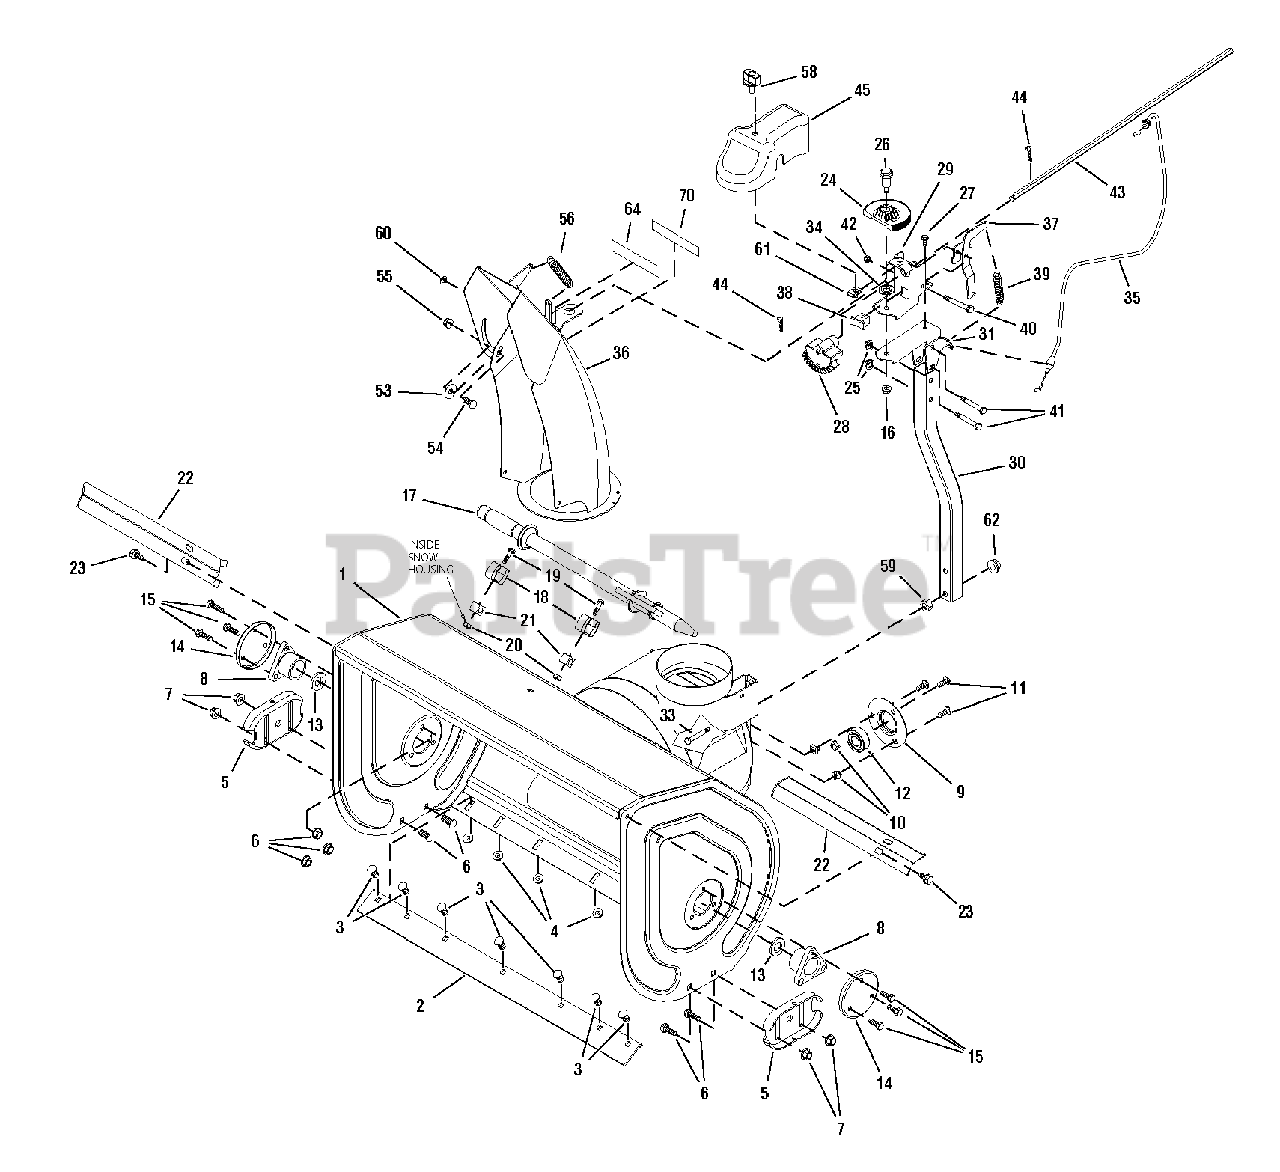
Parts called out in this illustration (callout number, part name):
1	HOUSING ASSEMBLY, 26"
1	HOUSING ASSEMBLY, 28"
1	HOUSING ASSEMBLY, 30"
1	HOUSING ASSEMBLY, 32"
2	BLADE, Scraper, 26"
2	BLADE, Scraper, 28"
2	BLADE, Scraper, 30"
2	BLADE, Scraper, 32"
3	CARRIAGE BOLT, 5/16-18 x 5/8 G5
4	NUT, Hex Flange 5/16-18 Two-Way Lock
5	SKID, Show Reversible
6	CARRIAGE BOLT, 3/8-16 x 3/4 G5
7	NUT, Hex Flange 3/8-16 ESNA
8	BEARING, Flange
9	BEARING RETAINER
10	RETAINER, Nut, 5/16-18
11	SCREW, Hex Whiz Lock Flange 5/16-18 x 3/4
12	BEARING
14	CAP, Bearing
15	CAPSCREW, Hex Head 5/16-18 x 7/8 G5
16	NUT, Hex Flange 5/16-18 Whiz Lock
17	STICK, Cleanout w/Brush
18	CLIP, Retainer
19	SCREW, Hex Washer Head Slot #10C x 1-1/4 G2
20	NUT, Hex Lock 10-24 w/Nylon Insert
21	BLOCK, Universal Pivot
22	CUTTER, Drift w/Tabs
23	SCREW, Hex Washer Head Taptitte 5/16-18 x 3/4
24	GEAR, 13 Tooth
25	NUT, Hex Keps 5/16-18 Conical Washer
26	BOLT, Shoulder 5/16-18 x 3/5 G5
27	SCREW, Hex Washer Head Taptite 1/4-20 x 1/2
28	GEAR, Sector 34 Tooth Powdered Metal
29	SUPPORT, Driver Gear
30	TUBE, Square 1-1/4
31	BRACKET, Gears Support
33	CAPSCREW, Hex Head 3/8-16 x 2 G5
34	WASHER, Powdered Metal
35	CABLE, Chute Brake 40" Long
36	CHUTE ASSEMBLY, Remote Deflector
37	BRACKET, Brake
38	ARM & PAD ASSEMBLY, Brake
39	SPRING, Extension
40	CAPSCREW, Hex Head 1/4-20 x 2-1/2 G5
41	CAPSCREW, Hex Head 5/16-18 x 2 G5
42	NUT, Hex Centerlock 1/4-20
43	ROD, Hex, Chute
44	PIN, Quick
45	COVER, Chute
53	WASHER, Nylon
54	CARRIAGE BOLT, 5/16-18 x 3/4 G5
55	NUT, Hex Flange 5/16-18 ESNA
56	SPRING, Extension
58	KNOB & SCREW ASSEMBLY, 10-24 x 3/5
59	NUT, Push Pal 3/8
60	NUT, Push for 5/16 Diameter Stud Capped
61	NUT, Retainer Speed #10-24 w/Extrusion
62	NUT, Hex Keps, 3/8-16 Conical Washer
64	DECAL, Orange Strip for Chute Hinge
70	DECAL, Orange Chute Hinge
